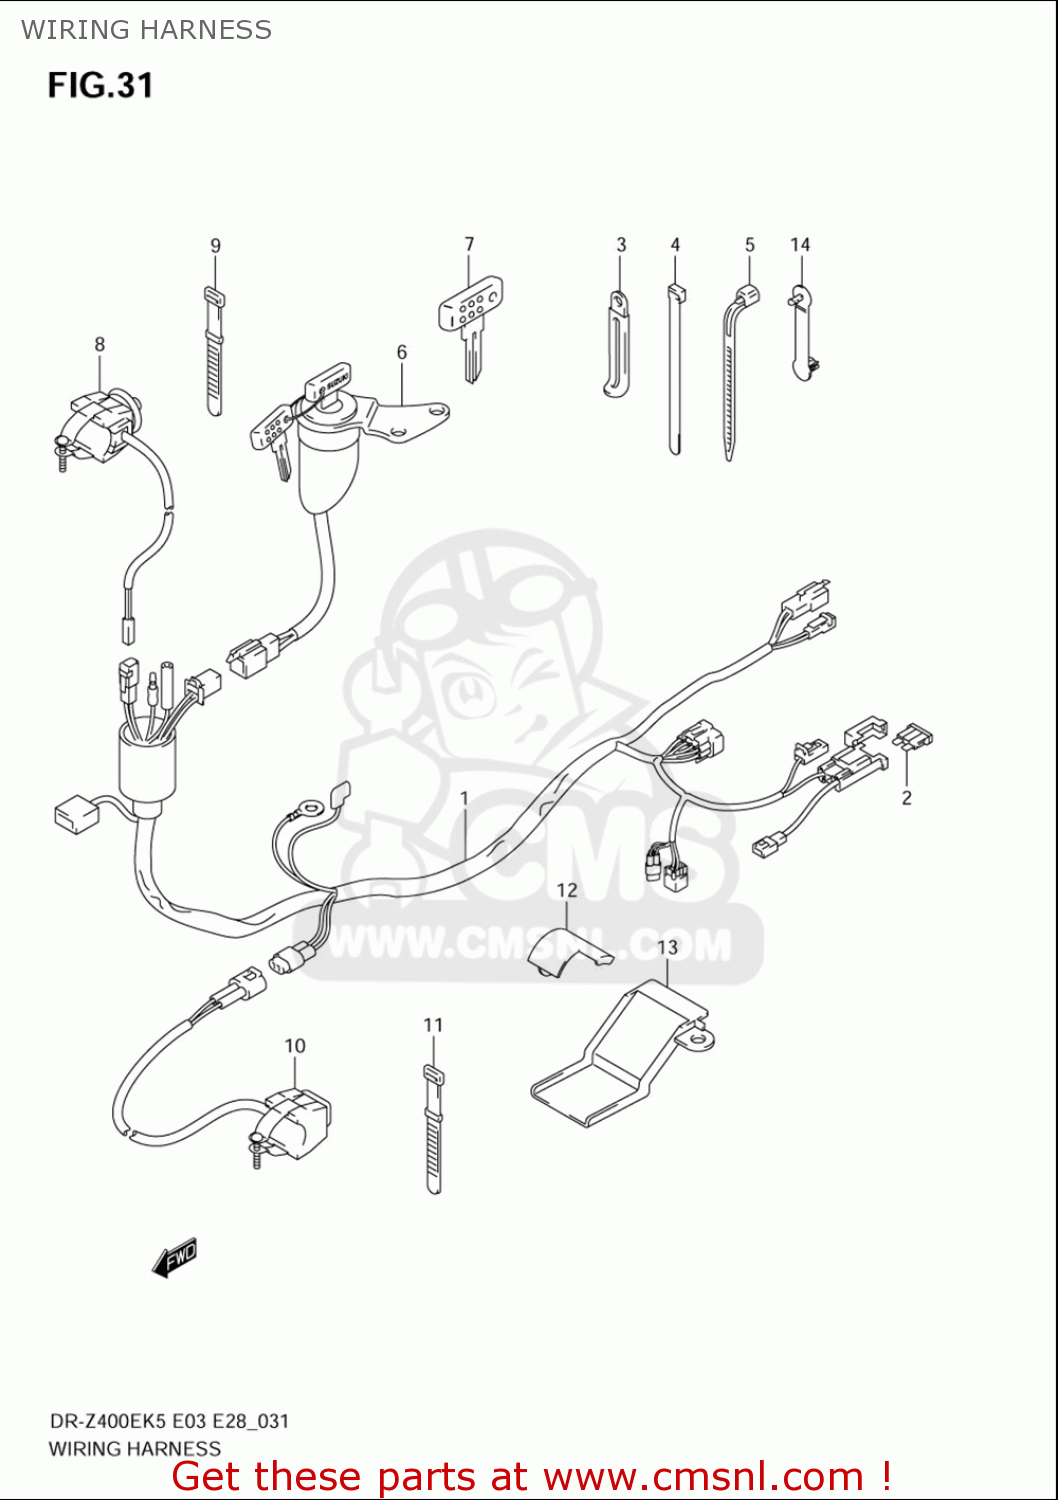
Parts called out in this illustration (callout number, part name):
1	HARNESS,WIRING
2	FUSE(10A)
3	CLAMP(L:65)
4	CLAMP(L:145)
5	CLAMP(L:125)
6	SWITCH ASSY,IGNITION
7	KEY,BLANK(TYPE:C)
8	SWITCH ASSY,STARTER
9	CLAMP(L:120)
10	SWITCH ASSY,ENGINE STOP
11	CLAMP(L:120)
12	PROTECTOR,WIRING HARNESS
13	PROTECTOR,WIRING HARNESS
14	CLAMP(L:63)
